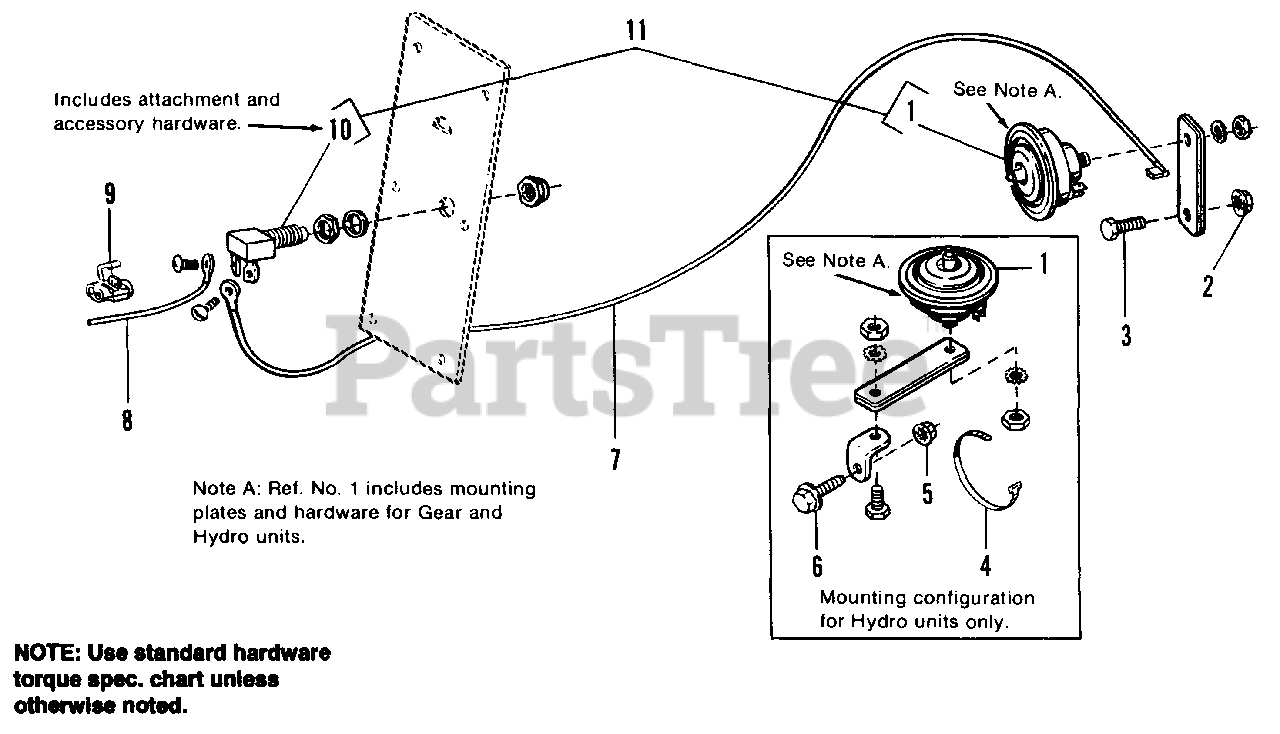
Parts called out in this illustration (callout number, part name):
1	HORN ASSY. (Included in Ref. No. 11)
2	NUT, Flange Whiz Lock, 1/4-20
3	CAPSCREW, Hex, 1/4-20 x 5/8
5	NUT, Flange Whizlock, 5/16-18
6	CAPSCREW, Taptite, 5/16-18 x 1
7	WIRE ASSY. (Black)
8	WIRE ASSY. (Red)
9	CONNECTOR, Wire, Self-Stripping
10	HORN BUTTON ASSY. (Included in Ref. No. 11)
11	HORN & BUTTON ASSY. (Incl. Ref. Nos. 1 & 10)
